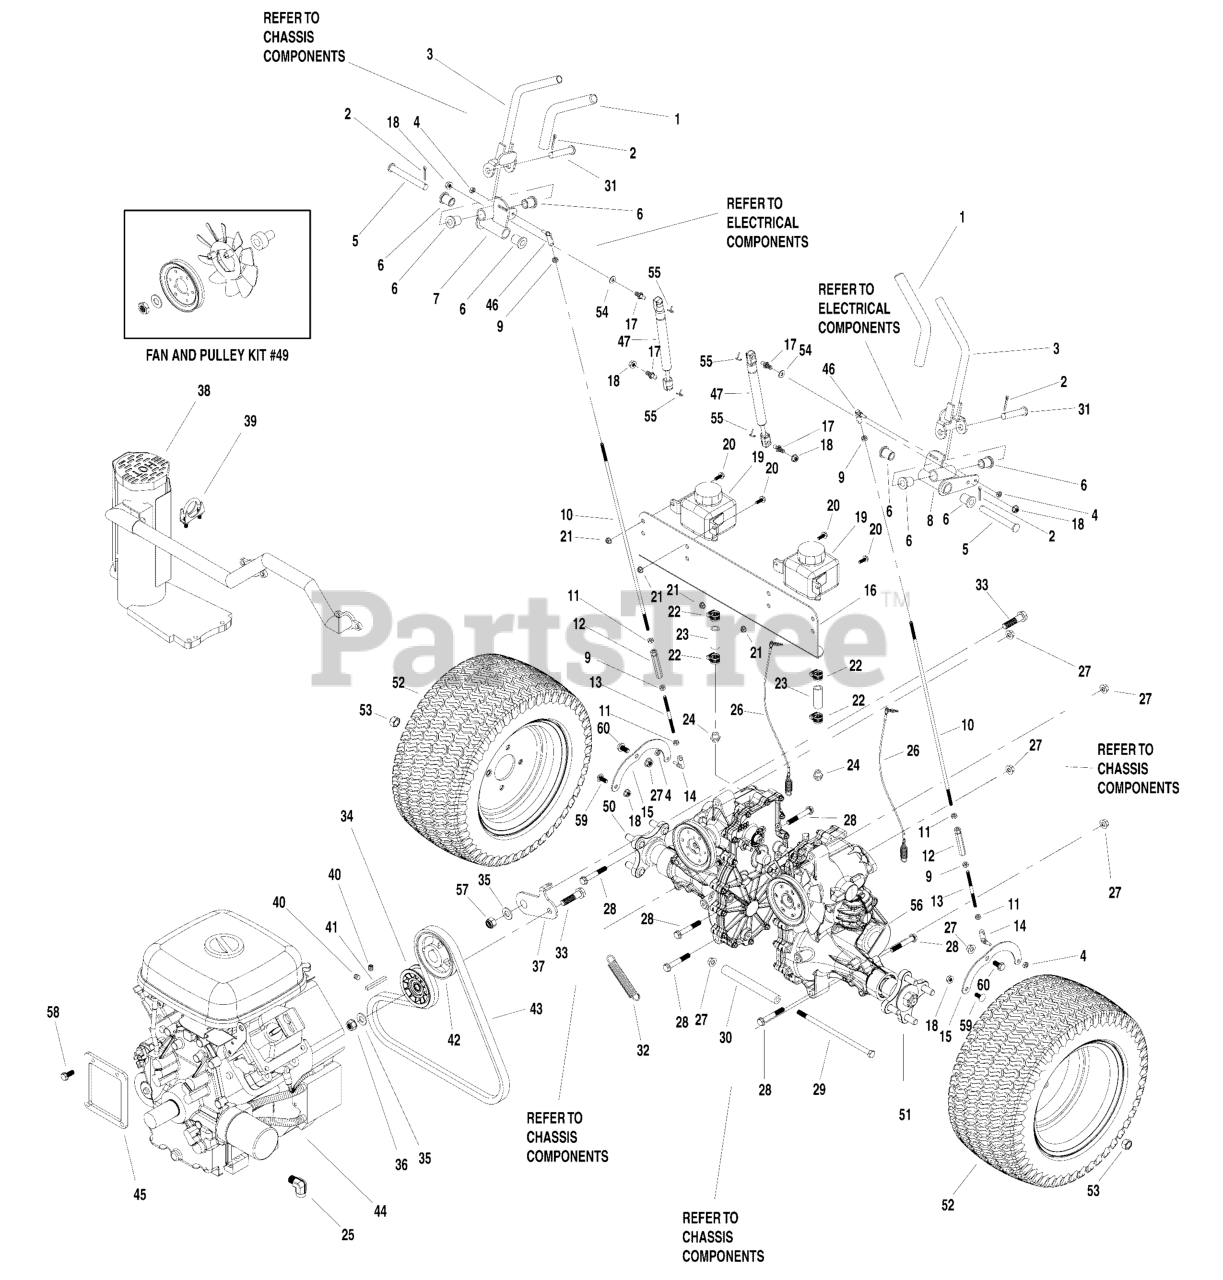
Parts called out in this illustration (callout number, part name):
1	GRIP, CONTROL, 9-1/2
2	PIN, COTTER, 1/8 X 1 1/2, CZ
2	BOLT, 1/4-20 X 3/4, FLANGE, CZ
3	NUT, 1/4-20, SERRATED FLANGE, YZ
4	NUT, 1/4-28, NYLOCK, CZ
5	PIN, CLEVIS, 1/2 X 4-1/2, YZ
6	BUSHING, 1/2 X 3/4 X 1F
7	WELD, CONTROL SWITCH BRACKET RH, CZ
8	WELD, CONTROL SWITCH BRACKET LH, CZ
9	NUT, 1/4-28, RH, GD5 CZ (15081)
10	ROD, 1/4-28 X 21
11	NUT, 1/4-28, LH, YZ
12	TURNBUCKLE, 1/4-28 X 3
13	ROD 1/4-28 X 4-1/2" YZ
14	KNUCKLE, 1/4-28 X 90DEG, LH (106-17-4637)
15	ARM, TRANSMISSION CONTROL (X3-1520)
16	MOUNT, OIL RESERVOIR - BLK
17	BALL, STUD
18	NUT, 5/16-18, FLANGE, YZ
19	TANK, HYDRO
20	BOLT, 1/4-20 X 3/4, FLANGE, CZ
21	NUT, 1/4-20, SERRATED FLANGE, YZ
22	CLAMP, OETIKER
23	HOSE, HYDRO
24	FITTING, STRAIGHT 7/16-20 UNF
25	VALVE, OIL DRAIN
26	CABLE, HYDRO NEUTRAL RLS
27	NUT, 3/8-16, FLANGE
28	BOLT, 3/8-16 X 2-1/2, FLANGE, CZ
29	BOLT, 3/8-16 X 9-1/2, CZ
30	SPACER, .75 OD X 6.40 LONG, 10GA
31	PIN, CLEVIS, 1/2 X 2-1/2, YZ
32	SPRING, IDLER, #98
33	BOLT, 1/2-13 X 2, CZ
34	PULLEY IDLER 3.0 OD .506ID .75
35	WASHER, 1/2 SAE, YZ (15124)
36	NUT, 1/2-13 SERRATED FLANGE, CZ
37	IDLER ARM (ZF15052)
38	KIT, MUFFLER, Z3
39	CLAMP, MUFFLER, Z3000
40	SET SCREW, 5/16-18, BLK
41	KEY, 1/4 SQ X 1-1/4
42	PULLEY, DRIVE
43	BELT, DRIVE, Z3000
45	PLATE, SPACER, Z3, CZ
46	KNUCKLE, 1/4-28 X 90, RH (103-17-4633)
47	DAMPENER
49	KIT, FAN/PULLEY
50	TRANSAXLE, ZT3100, RH, ZJ-LPRP-3A7C-19XX
51	TRANSAXLE, ZT3100, LH, ZJ-HPRP-3A7B-19XX
52	TIRE, 22 X 11-10 HT
53	NUT, 1/2-20, LUG
54	WASHER, 5/16, SPLIT LOCK, CZ (15082)
55	CLIP, DAMPER BALL STUD
56	FILTER, HYDRO OIL (425-52114)
57	* NUT, Lock, 1/2-13
58	BOLT, 3/8-16 X 1, SER FLG GD5, CZ (15062)
59	BOLT, 5/16-18 X 3/4, CARRIAGE YZ
60	BOLT, 3/8-16 X 3/4, FLANGE, CZ
